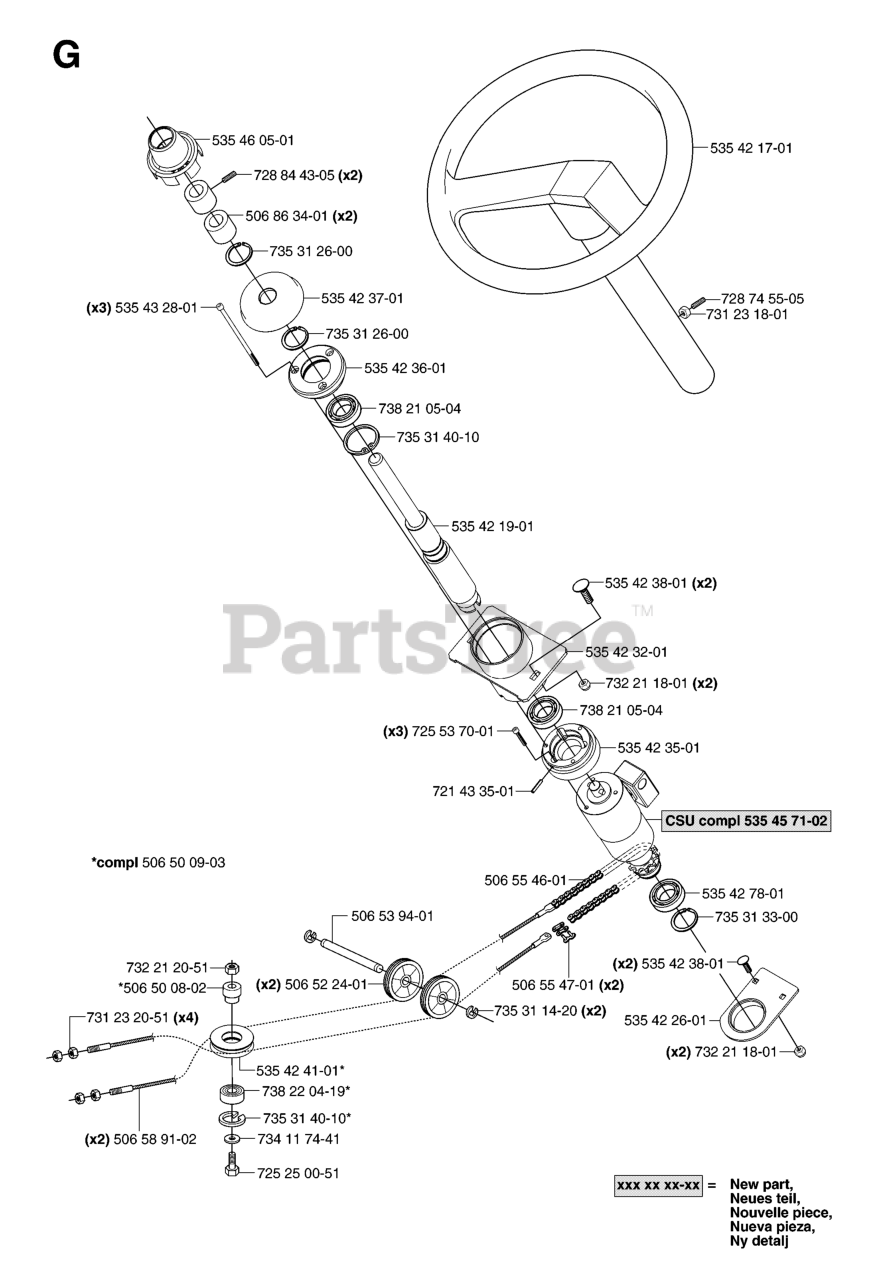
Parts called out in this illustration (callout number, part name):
2	STRETCH DRAWBAR
3	SCREW
4	Washer 13/32 X 3/4 X 16 Ga.
5	BUMPER.RUBBER.HOOD
9	DASH PANEL
10	BOLT D
11	PANEL DASH LH
17	HOOD
18	BUMPER HOOD T
20	PLATE MTG
23	BUSHING.SNAP.NYL.BLK.
25	WASHER
26	NUT
28	GRILL
29	LENS
31	BRACKET.SUPPORT.FENDER
37	Screw 5/16-18 x 1/2 Hex, Self Tapping 5/16-18 x 1/2
38	BRACKET LH PIVOT
39	BRACKET RH PIVOT
51	LOCKNUT.NYLOC.1/4-20
53	BRACKET PNT PICK OFF LT/PL
57	BOLT
58	AIR DUCT P/L/LT
60	Bolt - Rd. Hd. Sq. Neckiage 3/8 16 x 3/4
64	DASH LOWER
68	NUT
109	BRACKET BUMPER
110	PLUG PLASTIC
115	SCREW
134	ROD SUPPORT HOOD LT/PL HUS.
140	BRACKET SUSPENSION FRONT
142	PLATE
143	BRACKET, SWAY BAR
144	BRACKET FOOTREST
145	ROD PIVOT CHASSIS/HOOD
159	CUPHOLDER
